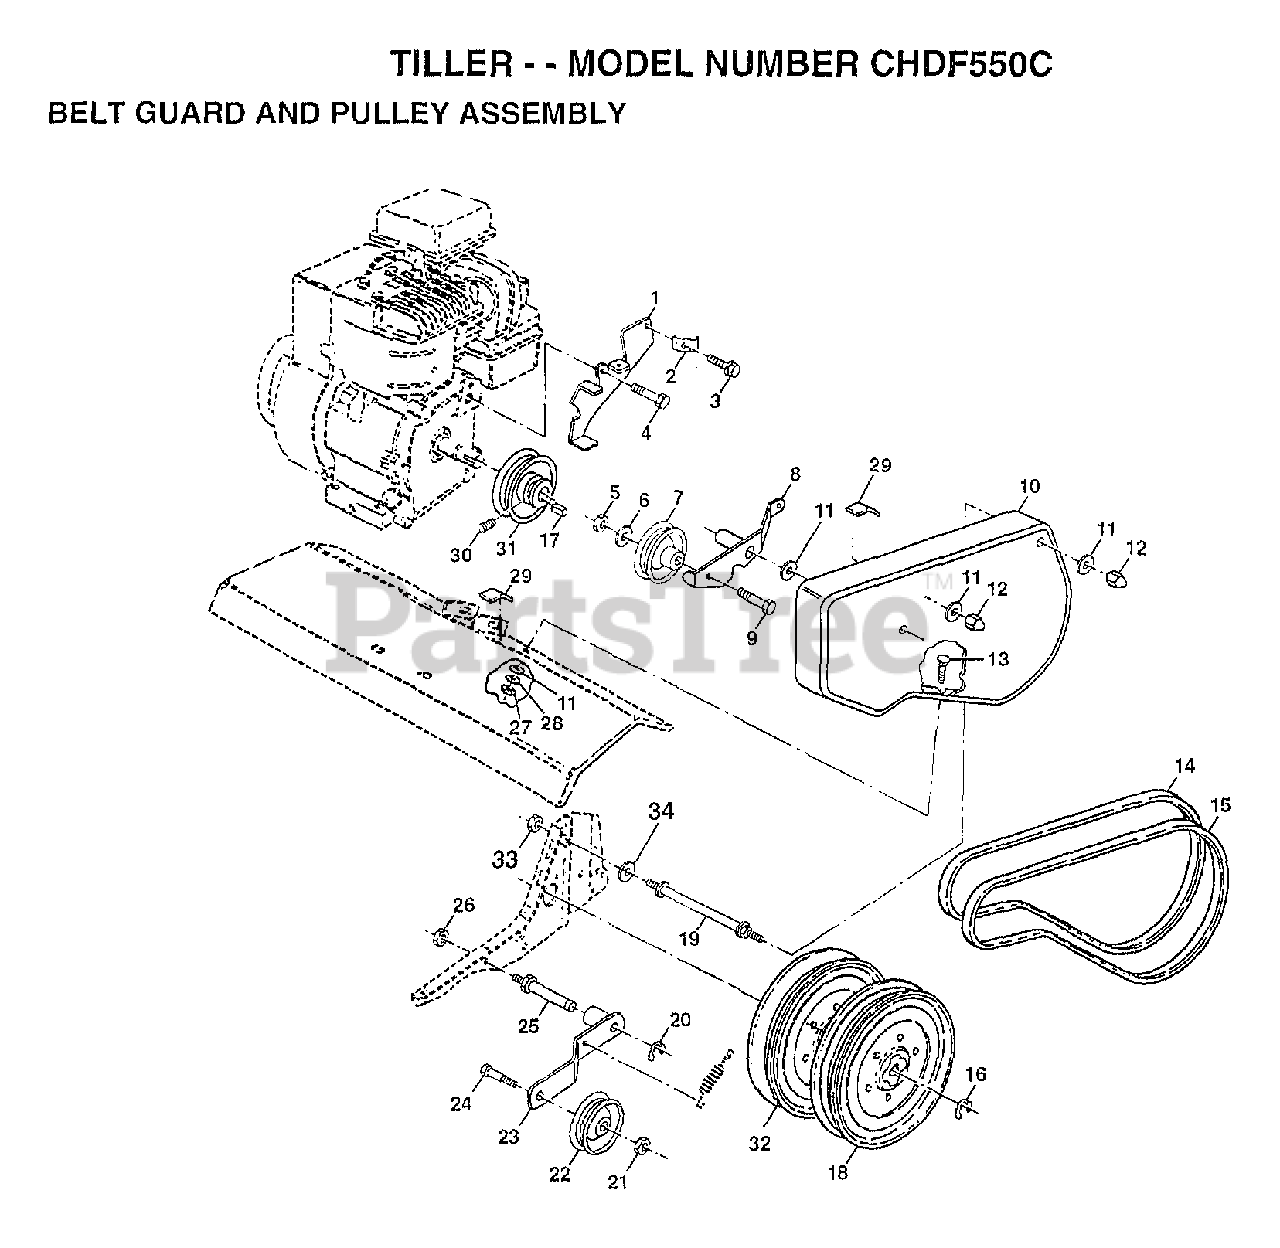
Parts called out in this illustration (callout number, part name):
1	ASM.BRKT.BELT.GRD
2	CONDIUT CLIP T
4	BOLT.HEX.HEAD
5	NUT.HEX.3/8-16UNC
6	WASHER
7	PULLEY W/SPACER
8	ARM.ASM.REV.IDLER
10	GUARD.PNT.BELT.MS-428
11	WASHER
12	NUT-CAP TI
13	BOLT T
14	BELT-V
17	KEY T
18	"SHEAVE,TRANS.""D"""
19	BOLT TI
20	KLIP RING TI
21	NUT
22	"PULLEY,IDLER"
23	"ARM, IDLER"
25	SHAFT IDLER TI
26	JAM NUT TI
28	LOCKWASHER
29	PAD IDLER TI
30	SET SCREW
31	ENGINE PULLEY TI
32	SHEAVE.TRANS
33	NUT
34	WASHER
